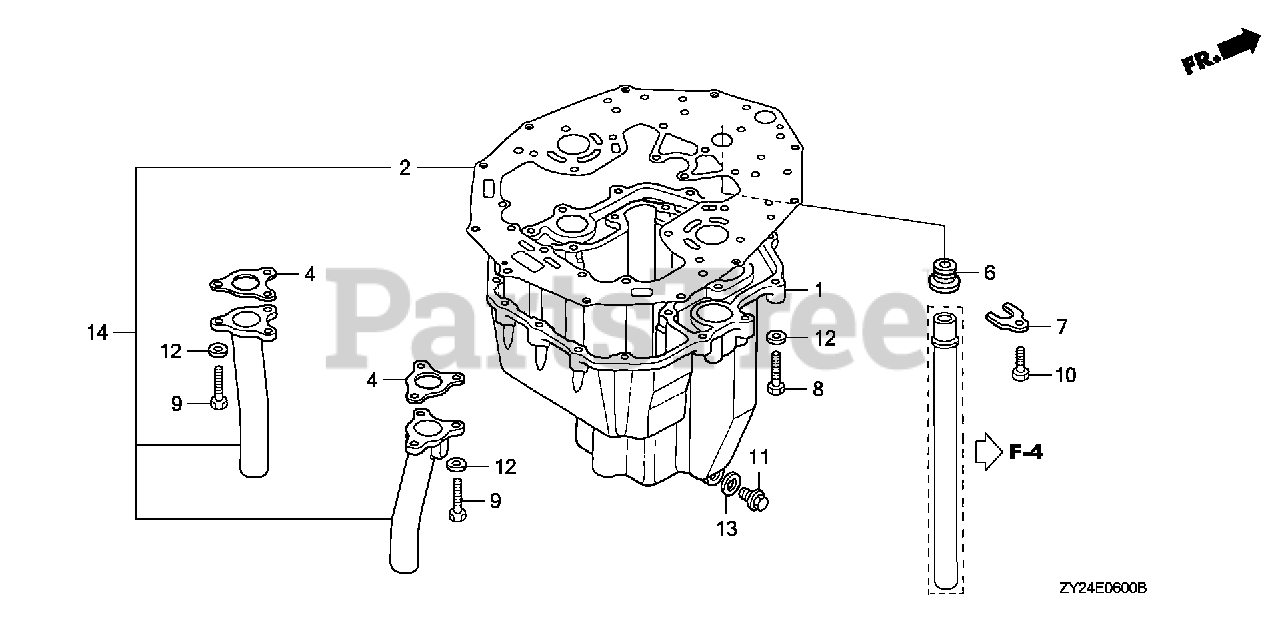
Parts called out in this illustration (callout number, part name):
1	PAN, OIL *TGRAY* (GRAY)
2	GASKET, OIL PAN
4	GASKET, EX. PIPE
6	GROMMET, WATER TUBE
7	PLATE, WATER TUBE
8	BOLT, HEX. (8X35)
9	BOLT, HEX. (8X28)
10	BOLT, HEX. (6X16)
11	BOLT, DRAIN PLUG
12	WASHER, PLAIN (8MM)
13	WASHER, DRAIN PLUG (12MM)
14	PIPE KIT, EX.
